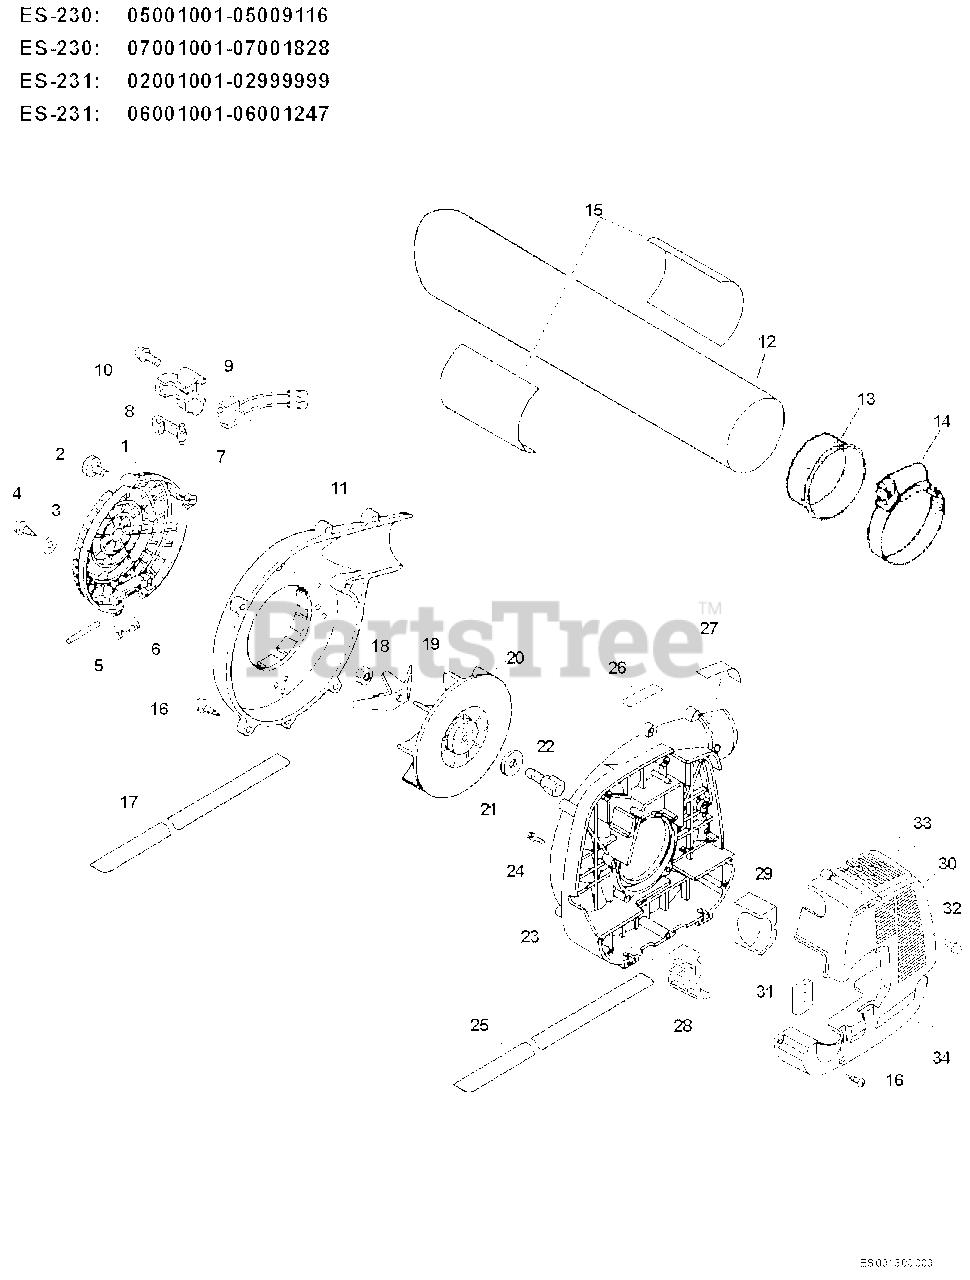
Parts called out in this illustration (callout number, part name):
1	GUARD, DEBRIS
2	THUMBSCREW
3	WASHER - 5
4	SCREW - 5X14
7	IGNITION SWITCH ASSY
8	LEVER, SHUT OFF ACTUATOR
9	BRACKET, SWITCH - GRAY
10	SCREW - 4X22
11	COVER, FAN - LEFT
12	TUBE, VACUUM
15	LABEL - SHRED 'N' VAC
16	SCREW - 5X20 -- TAPPING
17	CUSHION
19	BLADE, SHREDDER
21	WASHER - 8
22	HUB, FAN
23	COVER, FAN - RIGHT
24	SCREW - 5X20
25	CUSHION
26	LABEL - NOISE 70dB(A) CAT II
27	LABEL - CAUTION
28	CUSHION, FUEL TANK - LEFT
29	CUSHION, FUEL TANK - RIGHT
30	COVER, ENGINE
31	CUSHION, FUEL TANK - FRONT
32	SCREW - 5X20
33	LABEL - HOT SURFACE
34	LABEL - MODEL ES-231
34	LABEL - MODEL ES-230
